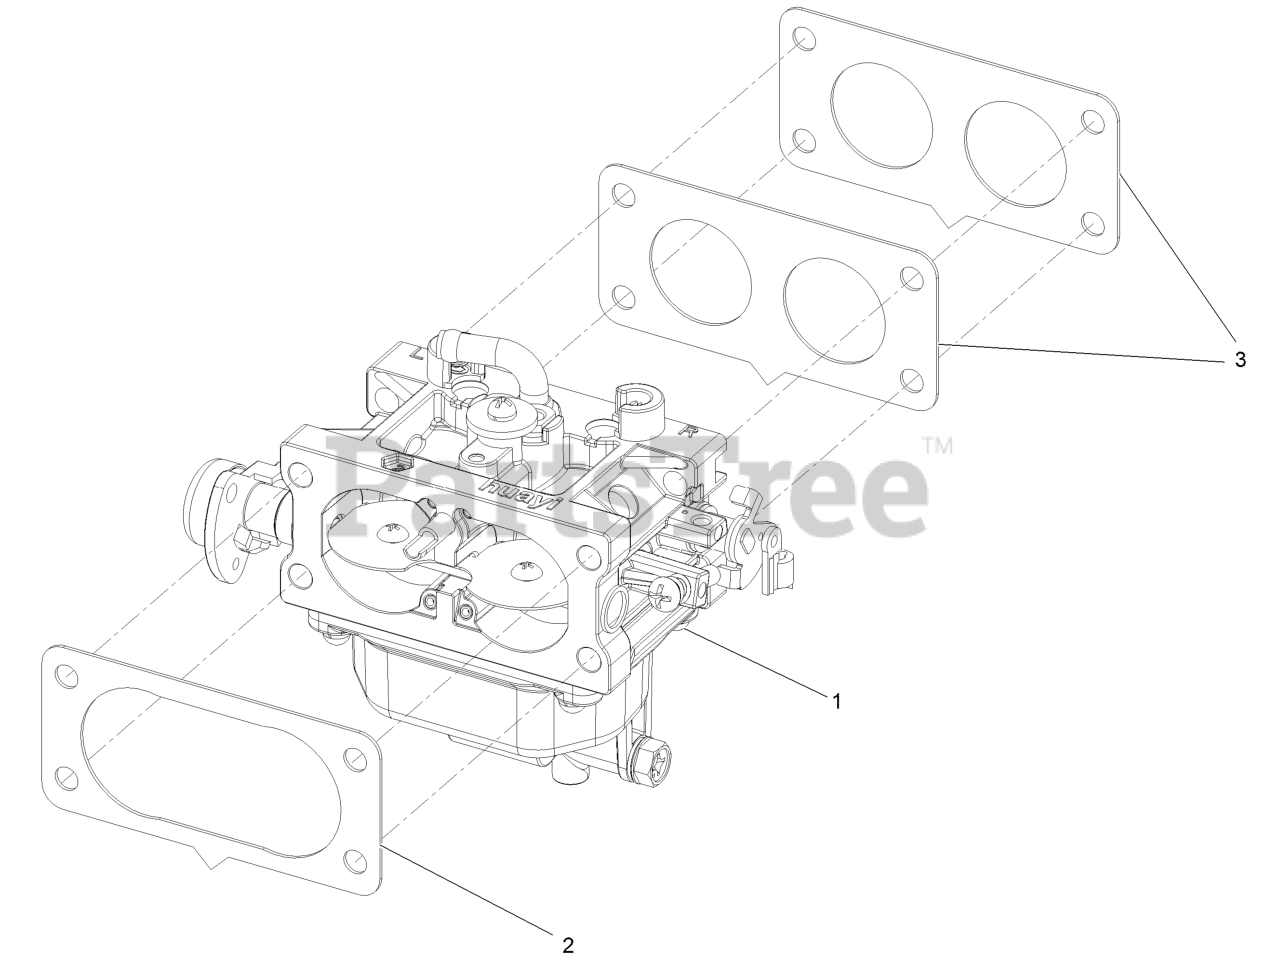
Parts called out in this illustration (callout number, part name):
1	Carburetor
2	Gasket-Carburetor
3	Gasket-Carburetor
